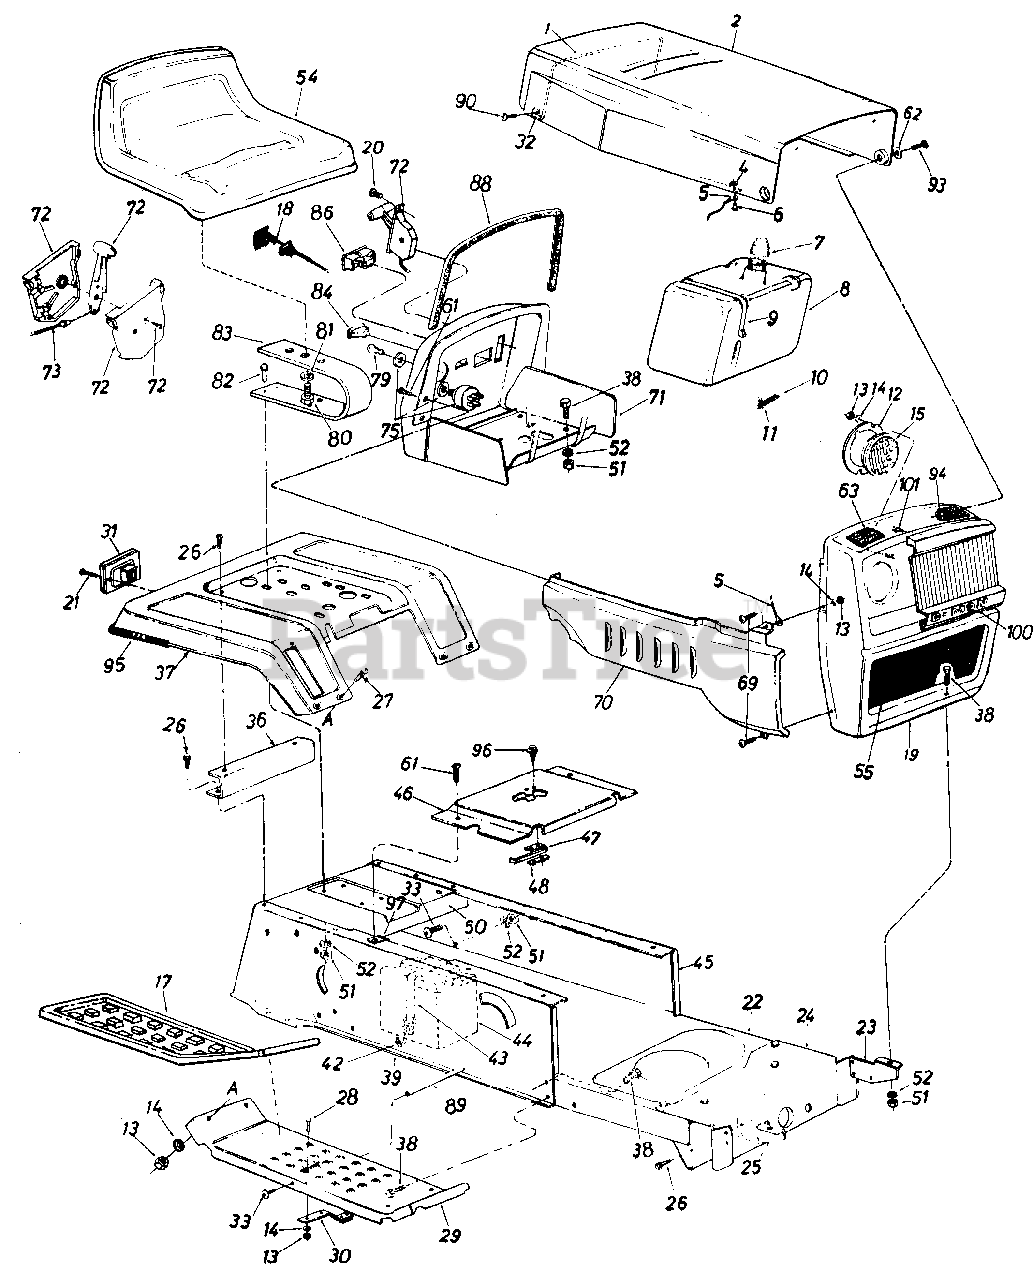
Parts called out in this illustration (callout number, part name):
1	Hood Spring
5	Hood Stop 7" Lg.
6	Pop Rivet
7	Fuel Cap Gauge
8	Fuel Tank
9	Tie Strap
10	Fuel Line
11	Hose Clamp
12	Headlight Retainer
13	Hex Nut 1/4-20 Thd.
14	L-Wash. 1/4" I.D.
15	Headlight
17	Foot Pad
18	Choke Control 29" Lg.
21	Truss AB-Tap Scr. #6 x .62" Lg.
22	Lower Frame
23	Grille Mount Brkt. L.H.
24	Front Pivot Brkt.
25	Grille Mount Brkt. R.H.
26	Hex Wash. Hd. AB-Tap Scr. 5/16 x .75" Lg.
27	Carriage Bolt 1/4-20 x 2.0"
28	Carriage Bolt 1/4-20 x .62"
29	Running Board
30	Blade Brake Ass'y.
31	Taillight
32	Hood Spring Retainer
33	Truss Mach. Scr. 5/16-18 x .75" Lg.
36	Fender Mount Brace
37	Fender
38	Hex Bolt 5/16-18 x .75" Lg.
39	R.H. Side Frame
42	Battery Strap Hook
43	Battery Hold Down Strap
44	12-V Battery
45	L.H. Side Frame
46	Shift Cover
47	Reverse Safety Switch
48	Insulator Nut Plate
50	Hitch Plate
51	Hex Nut 5/16-18 Thd.
52	L-Wash. 5/16" I.D.
54	Seat Ass'y.
55	Grille Insert
61	Truss Mach. Tap Scr. #10 x .50" Lg.
62	Washer .39" I.D. x .62" O.D.
63	Foam Strip 3/8 x 1-1/8 x 11/2
69	Truss Hd. Scr. 1/4-20 x .75"
70	R.H. Grille Side Panel
71	Dash Panel Ass'y.
72	Throttle Control Box Ass'y.
73	Throttle Control Wire
75	Ignition Switch
79	Ignition Key
80	Hex Bolt 1/2-13 x 1.0" Lg.
81	L-Wash. 1/2" I.D.
82	Hex Bolt 5/16-18 x 1.0"
83	Seat Spring 5.5" High
84	Light Switch
86	Ammeter
88	Molding Strip 27" Lg.
89	Running Board Rod
90	Self-Tap Scr. .5" Lg.
93	Shld Bolt .375 Dia. x .125
94	Hex L-Nut 1/4-28 Thd.
95	Trim Strip 81"
96	Hex Wash. Hd. AB-Tap Scr. #8 x .50" Lg.
97	Speed Nut #10Z
100	Bezel
101	Self-Tap Scr. #8 x .5" Lg.
